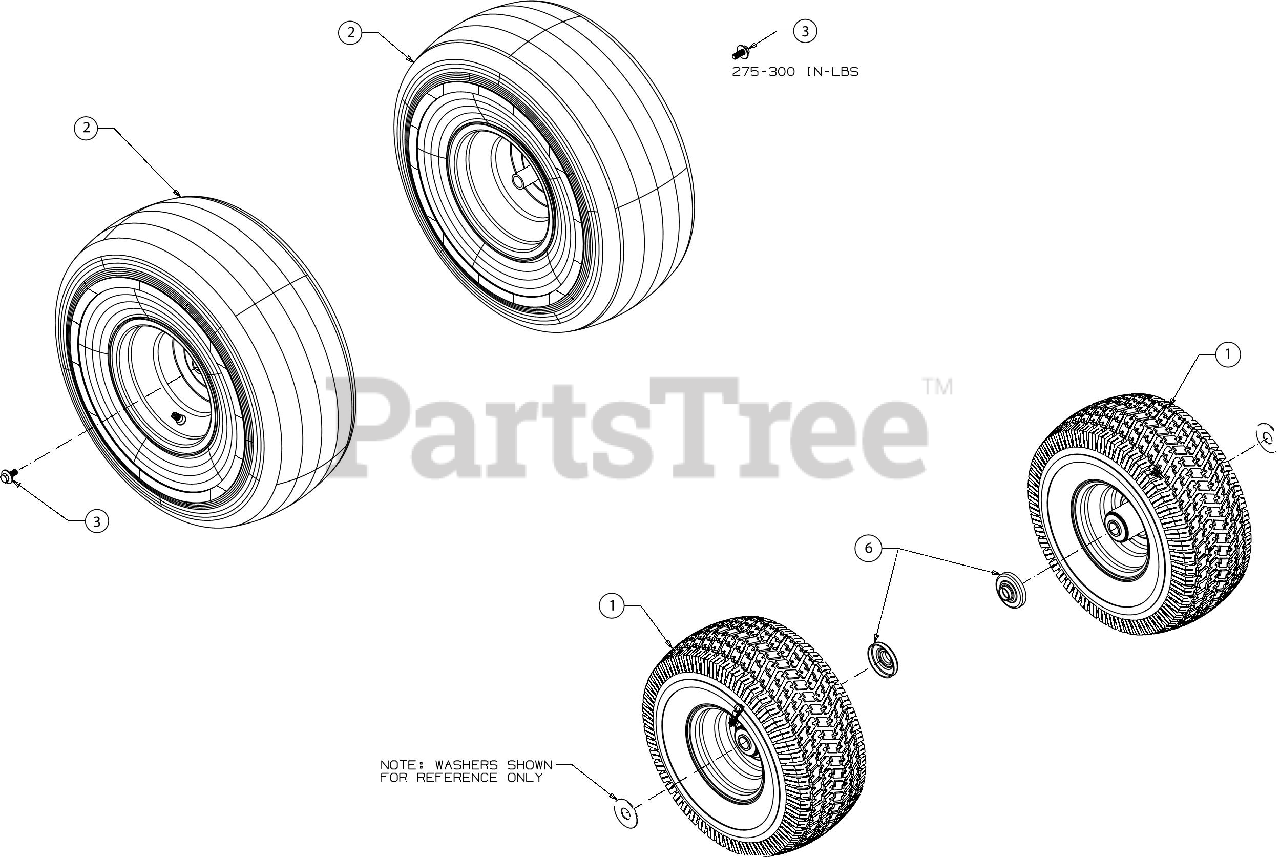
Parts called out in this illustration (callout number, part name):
1	WHEEL ASSEMBLY (15X6X6)
2	WHEEL ASSEMBLY (20X8X8)
3	SCREW 5/16-24 x .85 GR5
6	WHEEL BEARING COVER
